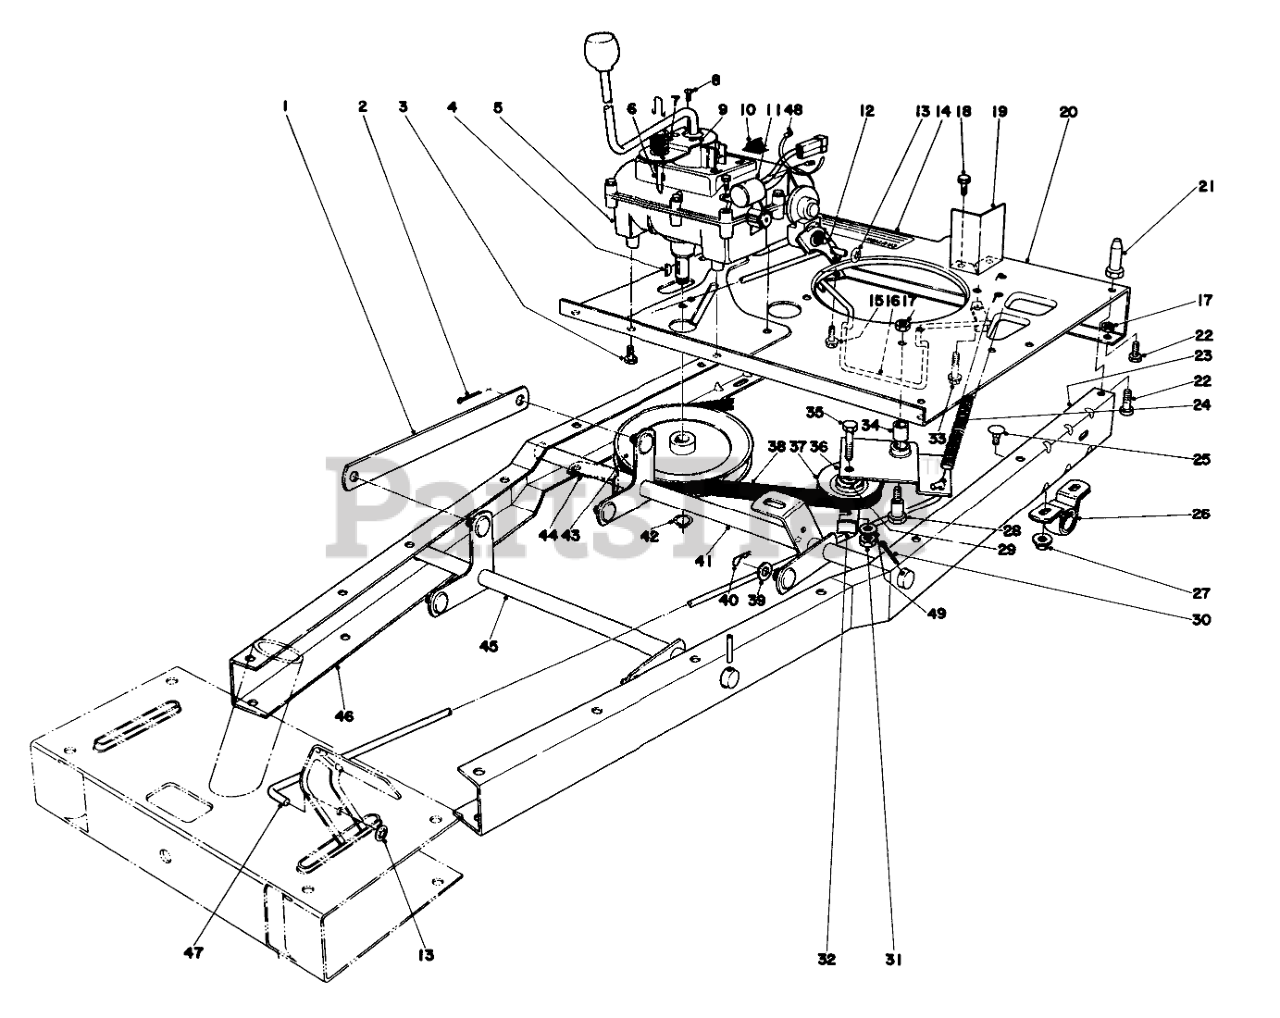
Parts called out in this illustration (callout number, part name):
1	Linkage-Height Adj.
2	PIN-COTTER
3	5/16-18 X 5/8 SEMS SC
4	KEY-WOODRUFF
5	Transmission 3 Speed
6	Neutral Spring Wire
7	SPRING
8	SCREW-HEAD, PAN
9	Neutral Bracket
10	Wire & Cable Tie
11	Control Module
12	Brake Return Spring
13	216 Washer
14	Decal
15	SCREW-HWHTF
16	Belt Guide
17	NUT-LOCK, CONE
18	SCREW-HH
19	Baffle-Carb
20	Plate-Engine Mounting
21	PIN-MOUNTING, LOWER
22	SCREW-HH
23	Frame Chanel, L.H.
24	Clutch Tension Spring
25	SCREW-CARR
26	PILLOW BLOCK
27	NUT-HF
28	CLUTCH PIVOT BOLT
29	Washer
30	PIN-COTTER
31	NUT-LOCK, CONE
32	RETAINER-BELT
33	Screw
34	BUSHING
35	SCREW-HH
36	Traction Idler (Incl. Ref. #34)
37	PULLEY-IDLER
38	V-BELT
39	WASHER-FLAT
40	PIN-COTTER
41	Height Adjustment
42	RING-SNAP, EXTERNAL
43	Pulley
44	TRANS BELT RET B
45	FRONT LIFT WA B
46	Frame Channel R.H.
47	Clutch Rod
48	Cable Tie
49	Washer
